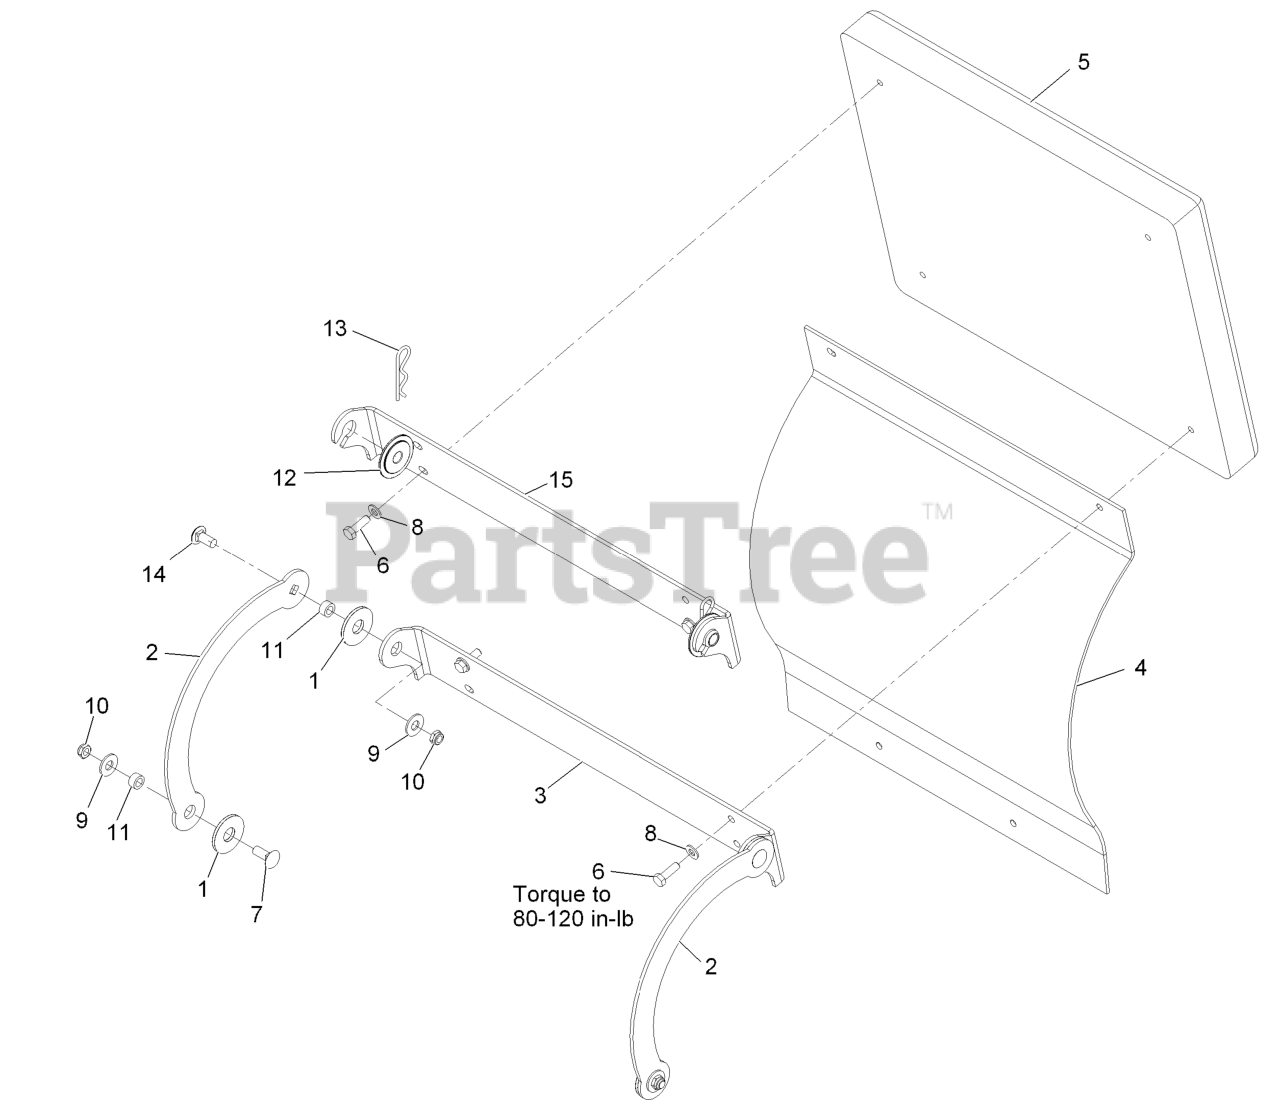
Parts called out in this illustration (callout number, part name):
1	WASHER-FRICTION, COMPOSIT
3	HINGE-PAD
5	PAD,GREY CUSHION
6	SCREW-HH, THREAD LOCKING
7	BOLT-CARR
8	WASHER-PLAIN
9	WASHER-FLAT
11	SPACER
12	SLIDE-BUSHING
13	PIN-HAIR
14	SCREW-CARR
15	HINGE-PAD
